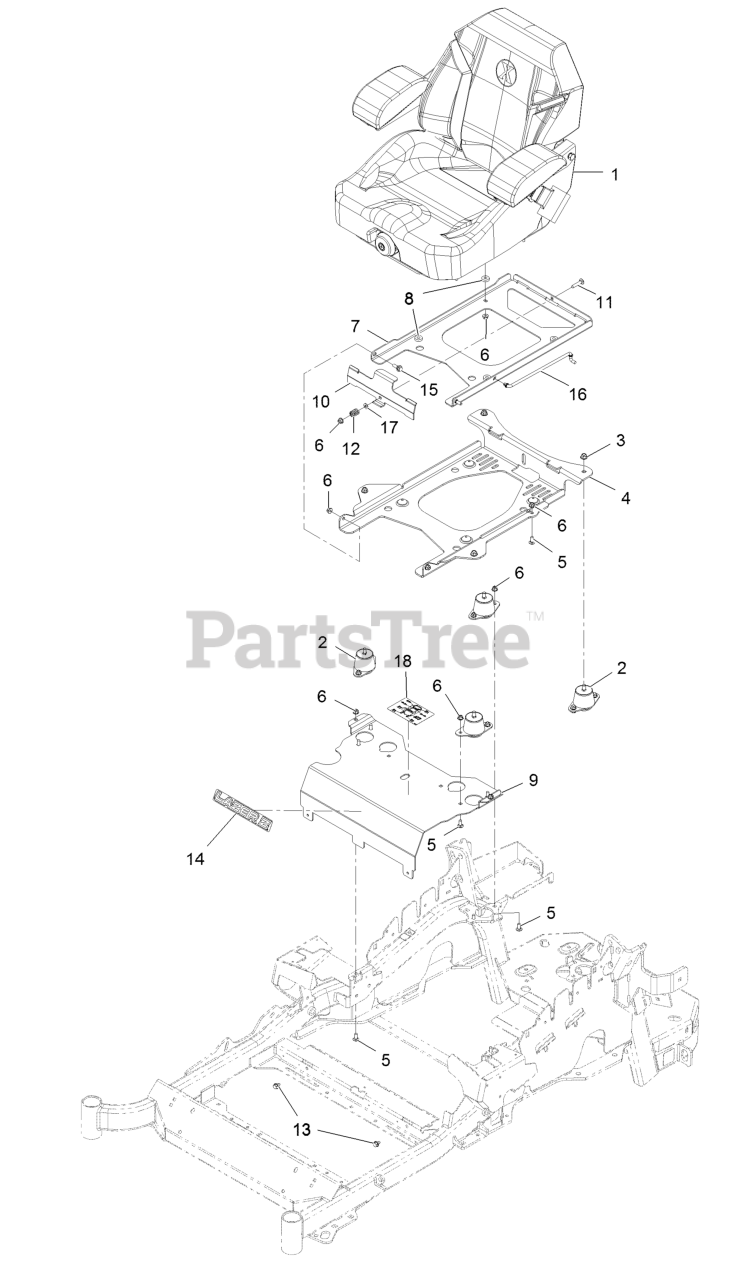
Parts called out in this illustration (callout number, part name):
1	KIT-SUSPENSION SEAT
2	ISOLATOR-SEAT
3	NUT-HF, NI
4	PLATE-TILT, SEAT SUPPORT
5	SCREW-CARR
6	NUT-HF, NI
7	PLATE-FRAME, SEAT
9	Panel-Front, Seat Mount
10	PLATE-LATCH, SEAT
11	BOLT-CARR
12	SPRING-COMPRESSION
14	DECAL, LAZER MODEL
15	SCREW-SHOULDER
16	ROD-PROP
17	WASHER-PLAIN
18	DECAL-SERVICE AID
